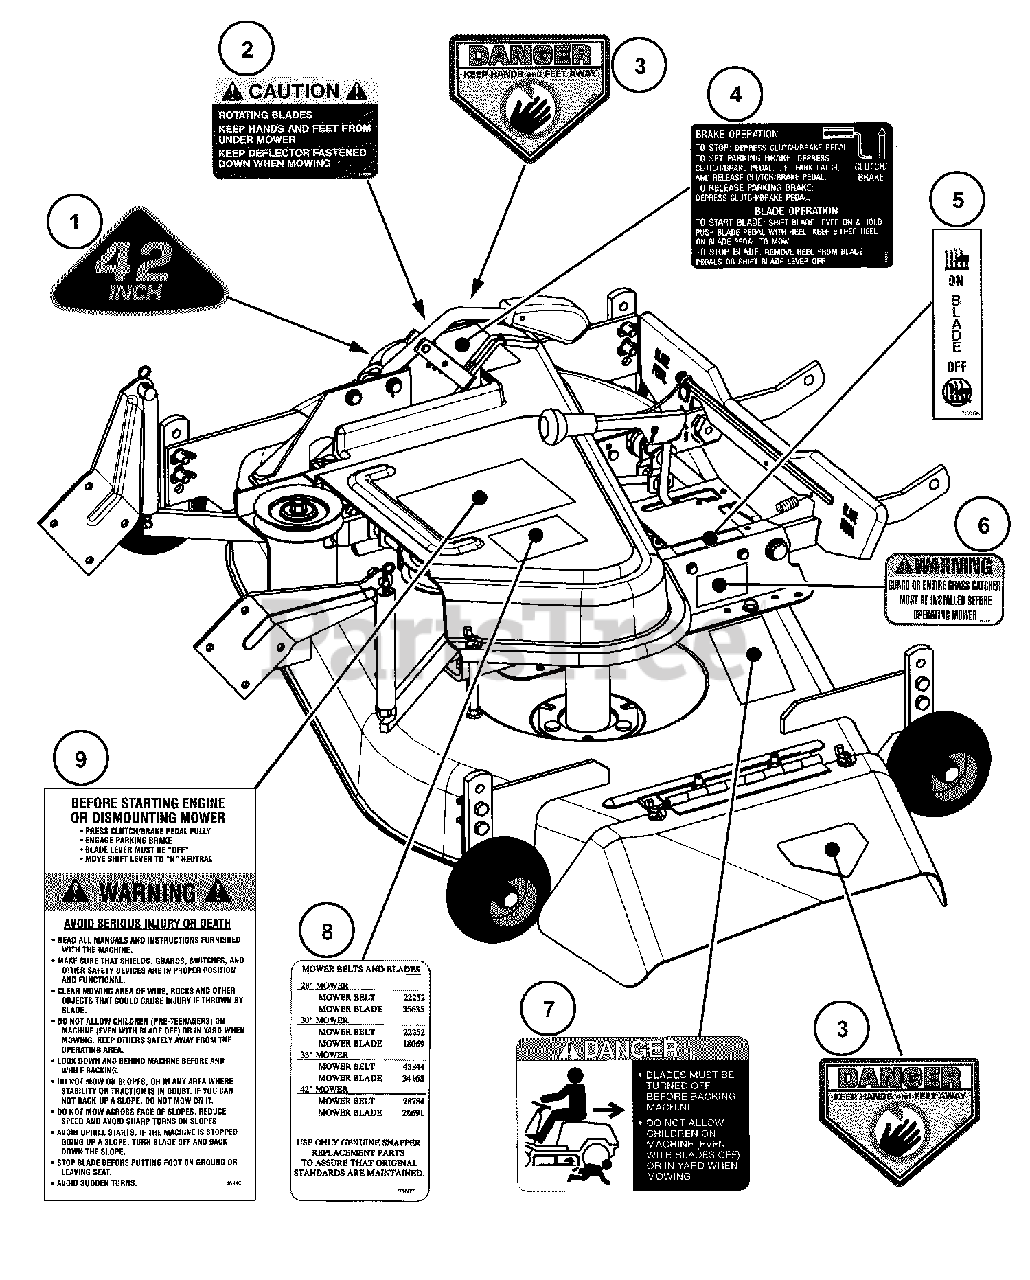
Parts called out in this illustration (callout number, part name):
1	DECAL - 42 INCH
2	DECAL, Caution
3	DECAL, Danger, Cut Finger
4	DECAL, Brake/Blade Operation
5	DECAL, Blade Engagement, 42" Deck
6	DECAL, Chute/Deflector
7	DECAL, No Mow In Reverse
8	DECAL, Service Parts, RER Domestic
9	DECAL, Safety Instructions
